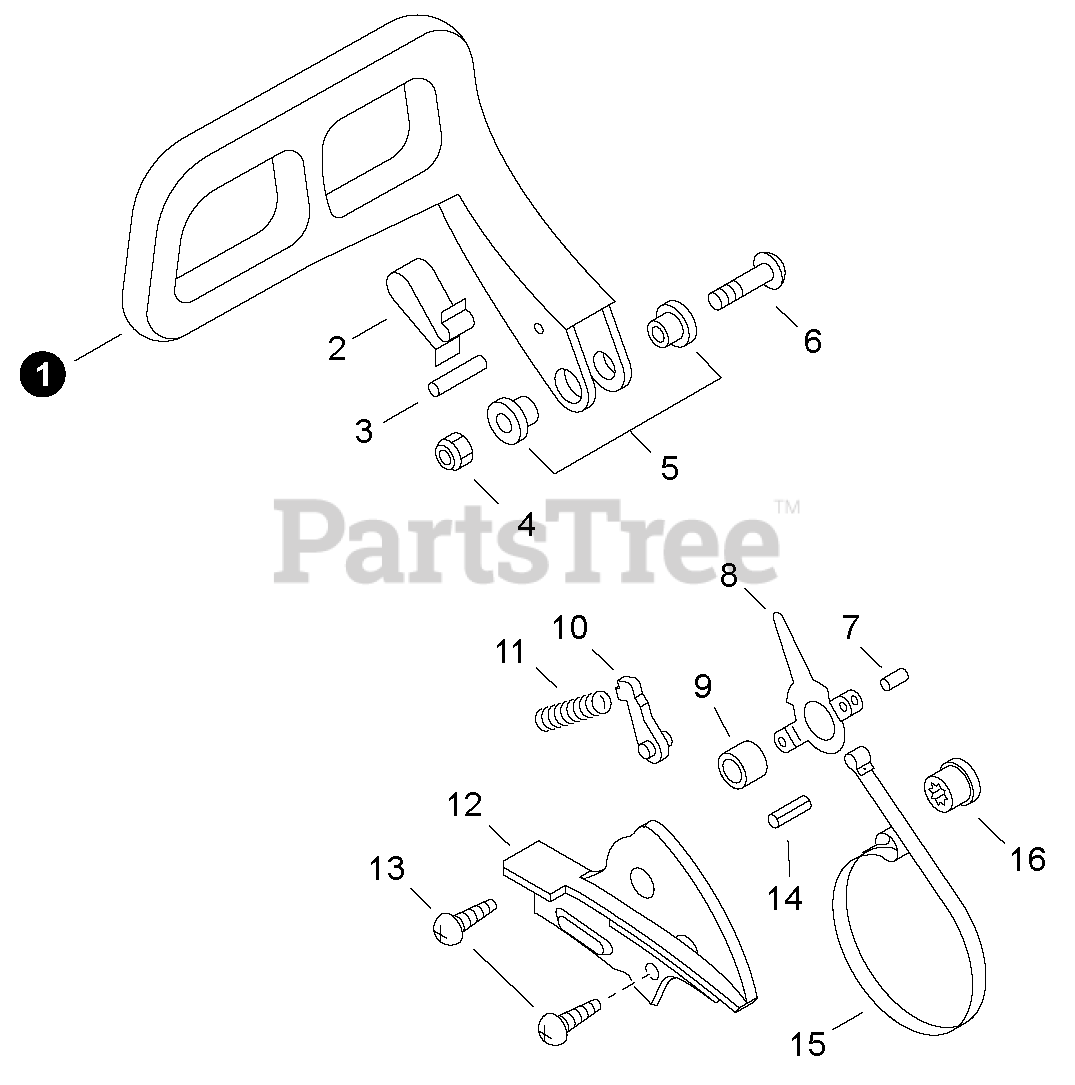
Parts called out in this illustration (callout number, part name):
1	LEVER, BRAKE
2	SPRING, FLAT
3	PIN 3×24
4	NUT, LOCK M5
5	COLLAR 5.3×10×13×L5
6	SCREW 5×32
7	PIN, SPRING 4×8.8
8	LEVER, BRAKE
9	WASHER 5.2×12×14
10	STOPPER, BRAKE
11	SPRING, COMPRESSION
12	COVER, BRAKE
13	SCREW 4×10
14	PIN, SPRING 2.5×12
15	BAND, BRAKE
16	ADJUSTER, BRAKE
